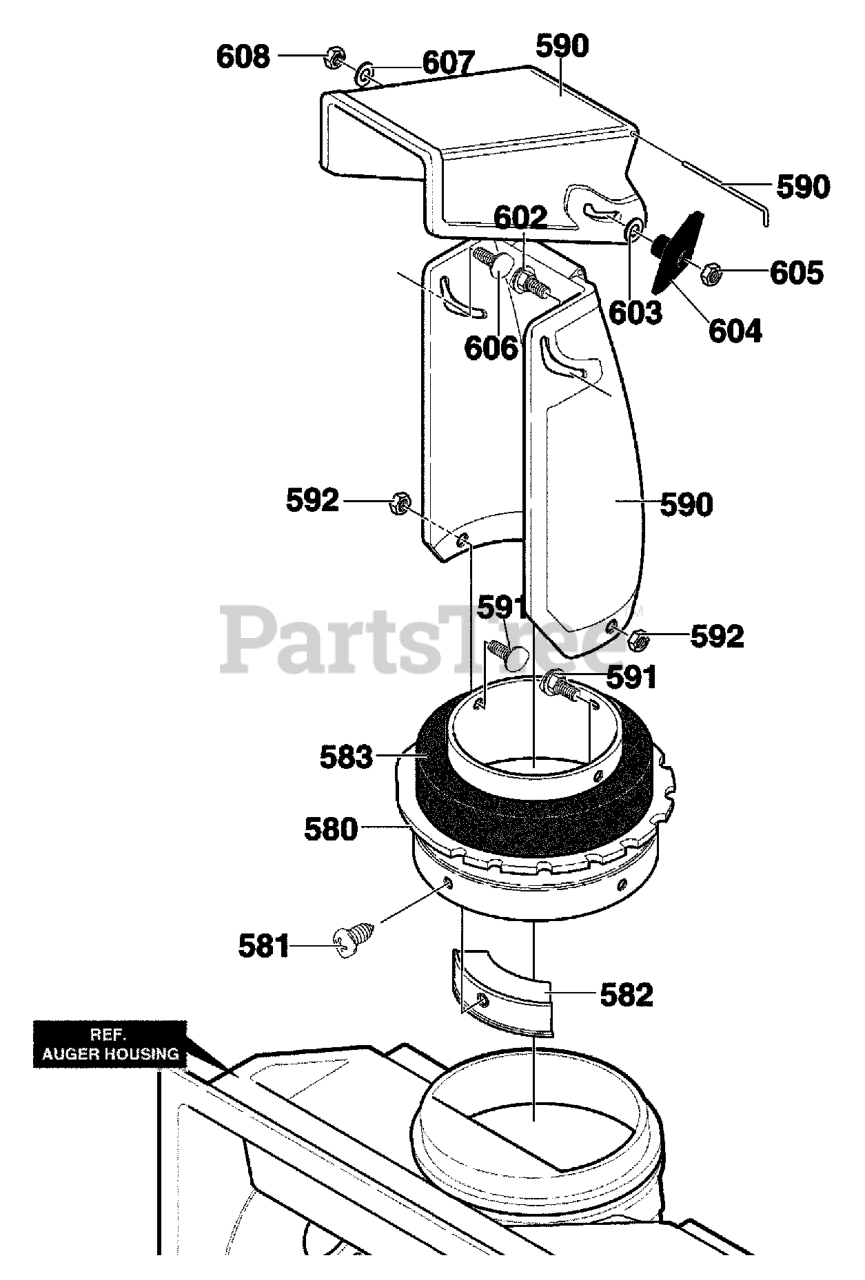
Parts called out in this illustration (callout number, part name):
580	RING, CHUTE
581	SCREW, #10X.50
582	GUIDE, CHUTE
583	DONUT FOAM
590	CHUTE ASSY.
591	SCREW 1/4-20X.50
592	NUT, 1/4-20
602	BOLT, 5/16-18X1.25 CARR.
603	WASHER, FLAT
604	KNOB, T
605	NUT, 5/16-18
606	SCREW, 5/16-18 x 0.75
607	WASHER, FLAT .349X.69X.066
608	NUT, 5/16-18
